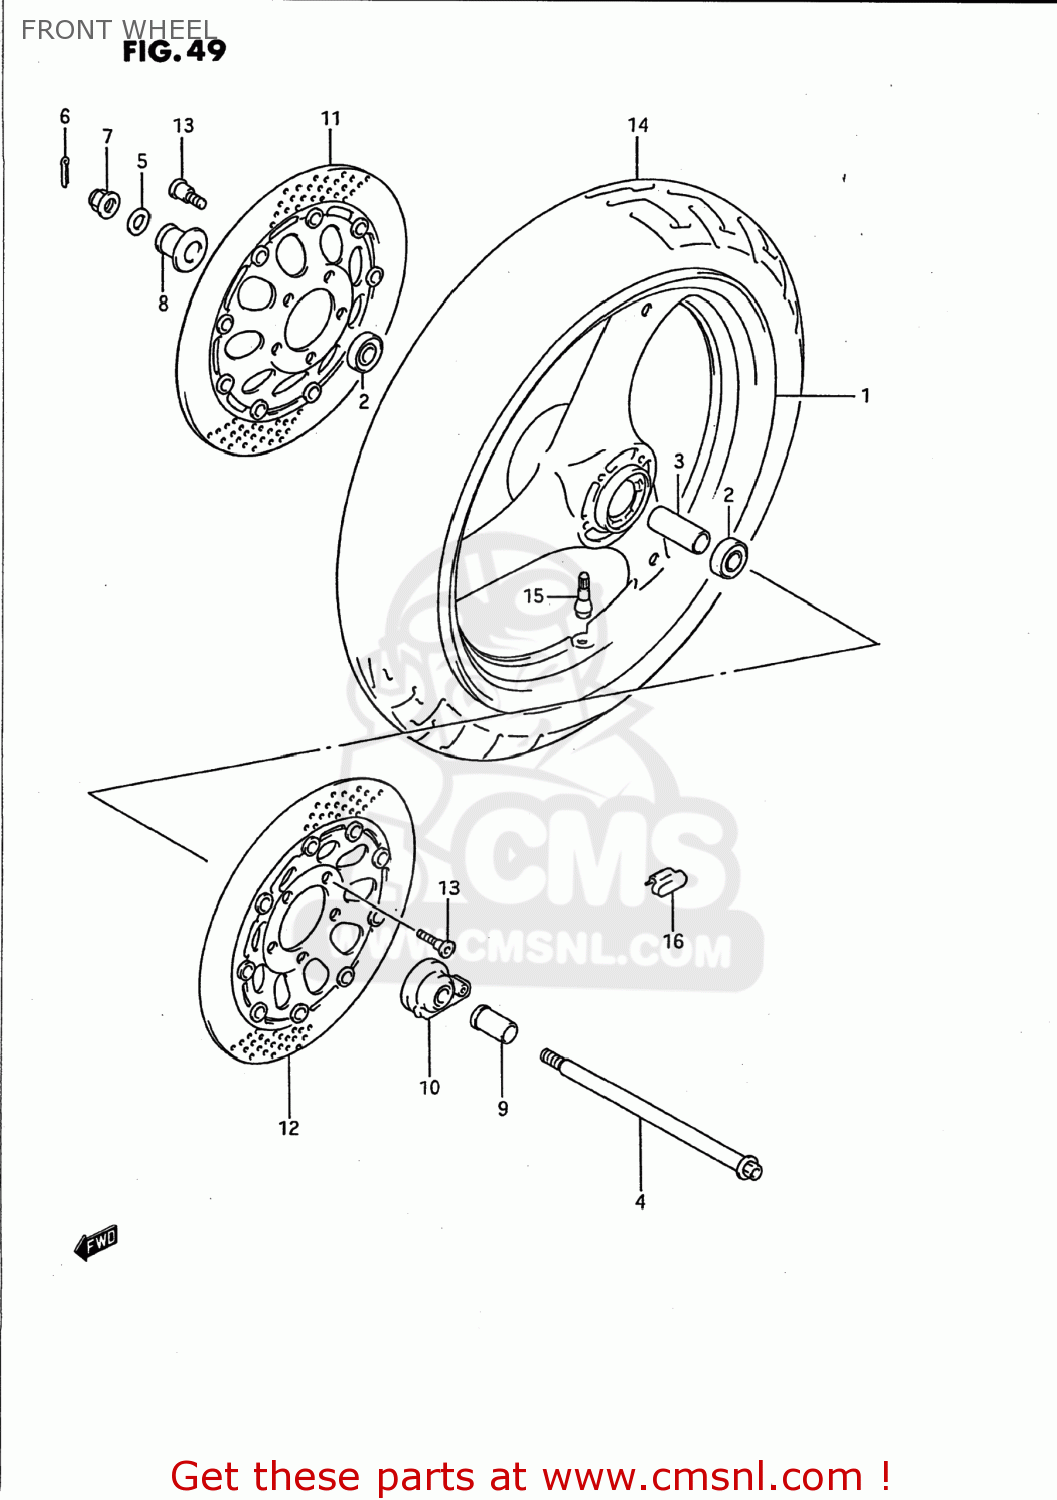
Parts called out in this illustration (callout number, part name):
1	WHEEL,FRONT (MT3.00X17)
2	BEARING
3	SPACER(15.3X21.7X63)
4	AXLE,FR
5	WASHER
6	COTTER PIN
7	NUT
8	SPACER,FR AXLE
9	SPACER,FR AXLE,L
10	BOX ASSEMBLY,SPEEDOMETER GEAR
11	DISC,BRAKE
12	DISC,BRAKE
13	BOLT 8X33
14	TIRE,FRONT
15	VALVE ASSEMBLY,WHEEL,TR412
16	BALANCER,WHEEL
